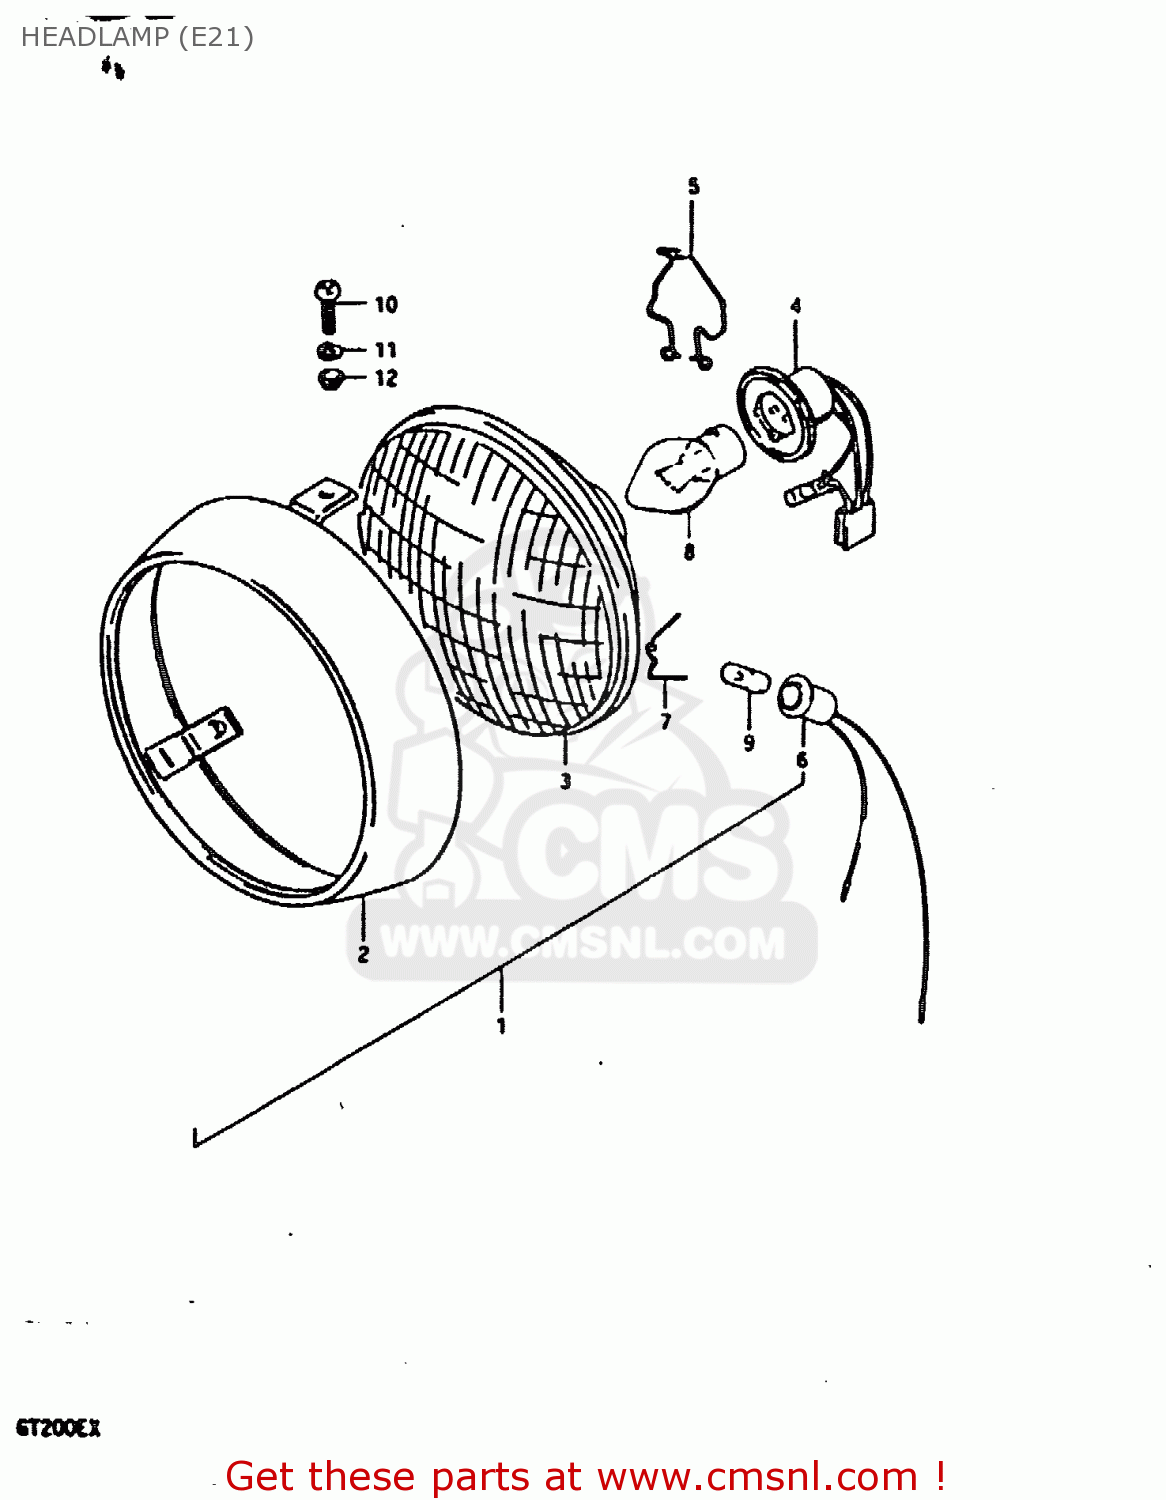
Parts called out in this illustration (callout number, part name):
1	HEADLAMP ASSY
2	RIM
3	UNIT
4	SOCKET
5	CLAMP,HEADLAMP
6	SOCKET
7	SPRING,HEAD LAMP UNIT
8	BULB(12V35/35W)
9	BULB(12V4W)
10	SCREW
11	WASHER,LOCK
12	WASHER
